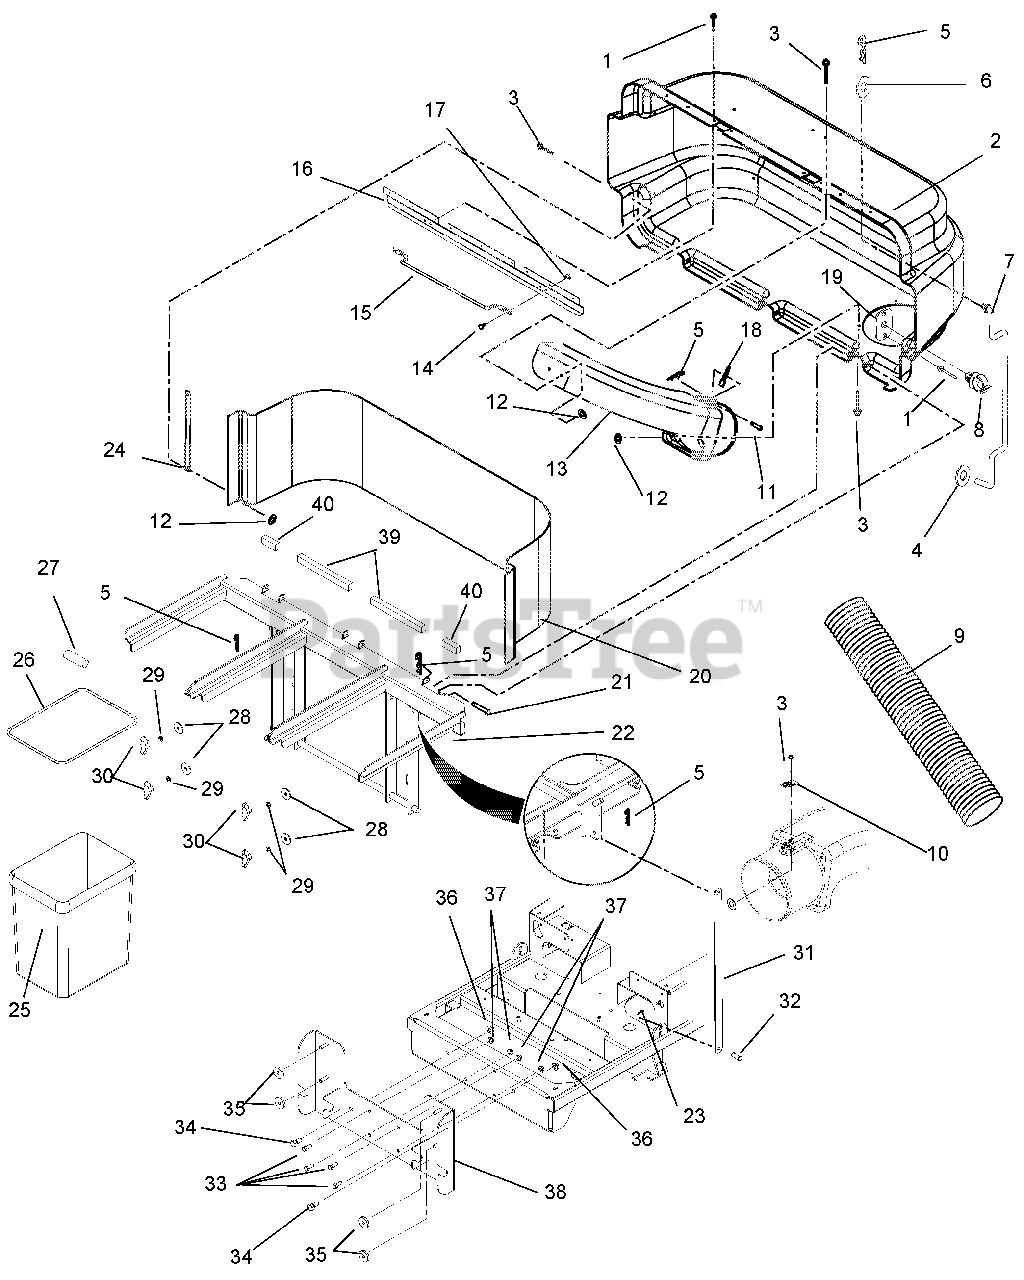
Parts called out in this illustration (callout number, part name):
1	Rivet, Pop .187 x .402
2	Cover, Bagger with Decal
3	Rivet, Pop .187 x .375
4	Retainer, .38 Push-On
5	Pin, Hair
6	Washer-Flat-Steel .046 x .812 x .065
7	Prop Rod, Bagger
8	Clip .38
9	Bagger Hose 45"
10	Thumb Latch
11	Pin, Clevis .31 x 2.62 Grade 5
12	Washer, Flat-Steel .219 x .50 x .049
13	Boot, Upper
14	Bolt, Round Head Square Neck .25-20 x .75 Grade 5
15	Bagger Handle
16	Latch, Cover
17	Nut, Locking-Top-Flange .25-20
18	Indicator, Flow
19	Plate, Rod Clip
20	Screen, Bagger
21	Pin, Clevis .368/.373 x 3.25
22	Weldment, Bagger Frame
23	Pin, Hair, External- #16
24	Strap, Cover
25	Bag, Mesh
26	Frame, Bag
27	Hose, .38 x .50 x 3.00 Vinyl
28	Washer, Flat Steel .390 x 1.5 x .125
29	Washer, Lock .38 x .094
30	Knob, Wing .38-16
31	Strap, Bagger
32	Pin, Clevis .38 x .75
33	Bolt, Hex .38-16 x 1.00 Grade 5
34	Bolt, Hex .50-13 x 1.00 Grade 5
35	Washer, Flat Steel .406 x 1.50 .245
36	Nut, .50-13 Nyloc Flange
37	Nut, .38-16 Nyloc Flange
38	Mount, Rear Bagger
39	Grass Block, 10.5-In. Foam
40	Grass Block, 4-In. Foam
